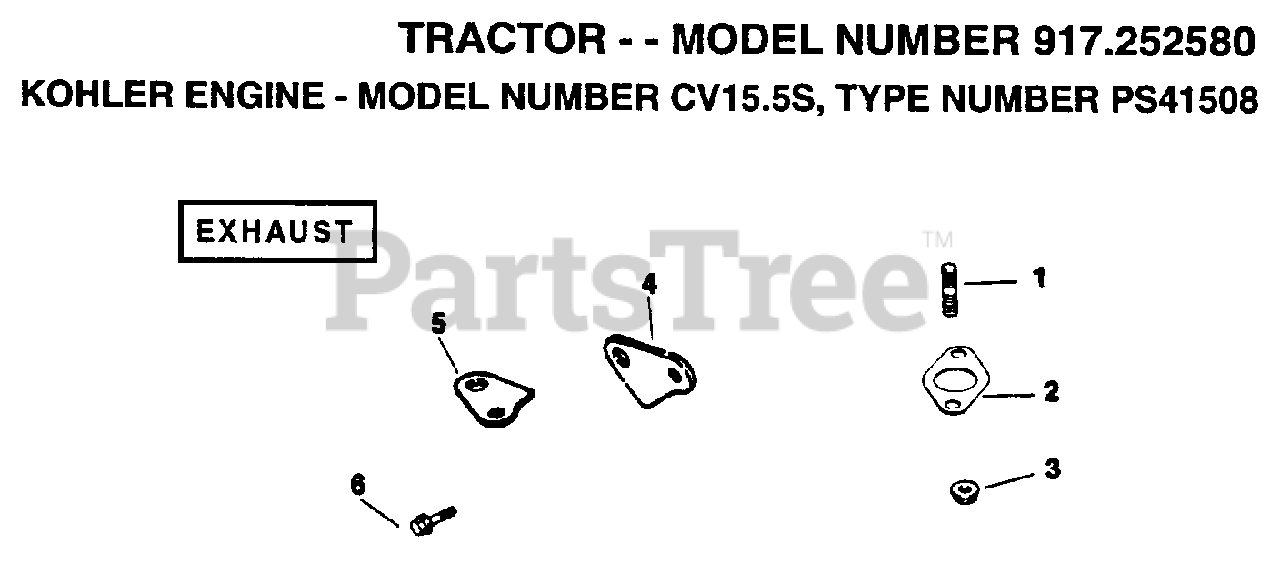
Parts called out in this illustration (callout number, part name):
1	STUD. EXHAUST MANIFOLD
2	GASKET, EXHAUST MANIFOLD
3	NUT, MUFFLER MOUNTING
4	BRACKET, MUFFLER
5	STRAP, LIFTING
6	SCREW, LIFTING STRAP
